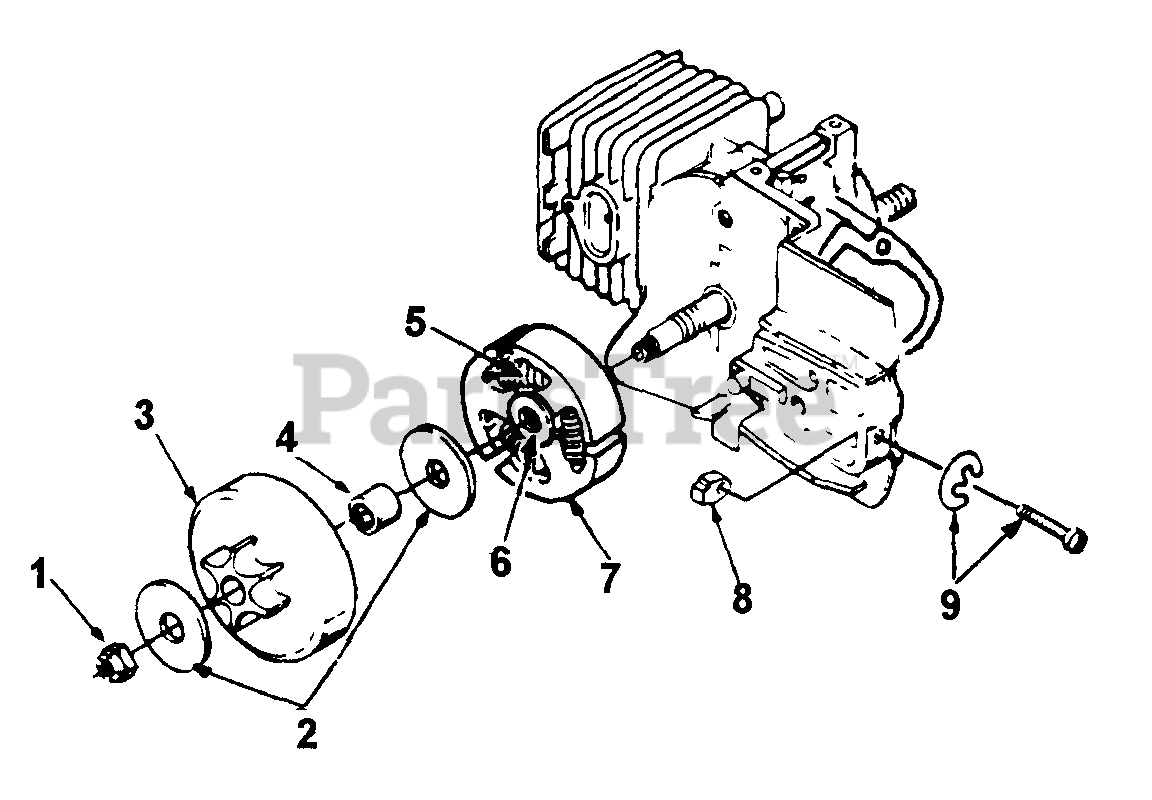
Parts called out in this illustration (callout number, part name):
1	NUT, (5/16 -24)
2	WASHER, THRUST
3	SPROCKET & DRUM
4	BEARING
5	SPRING, CLUTCH
6	SPIDER, CLUTCH
7	SHOE, CLUTCH
8	PIN, ADJUSTING
9	SCREW & E-RING KIT
